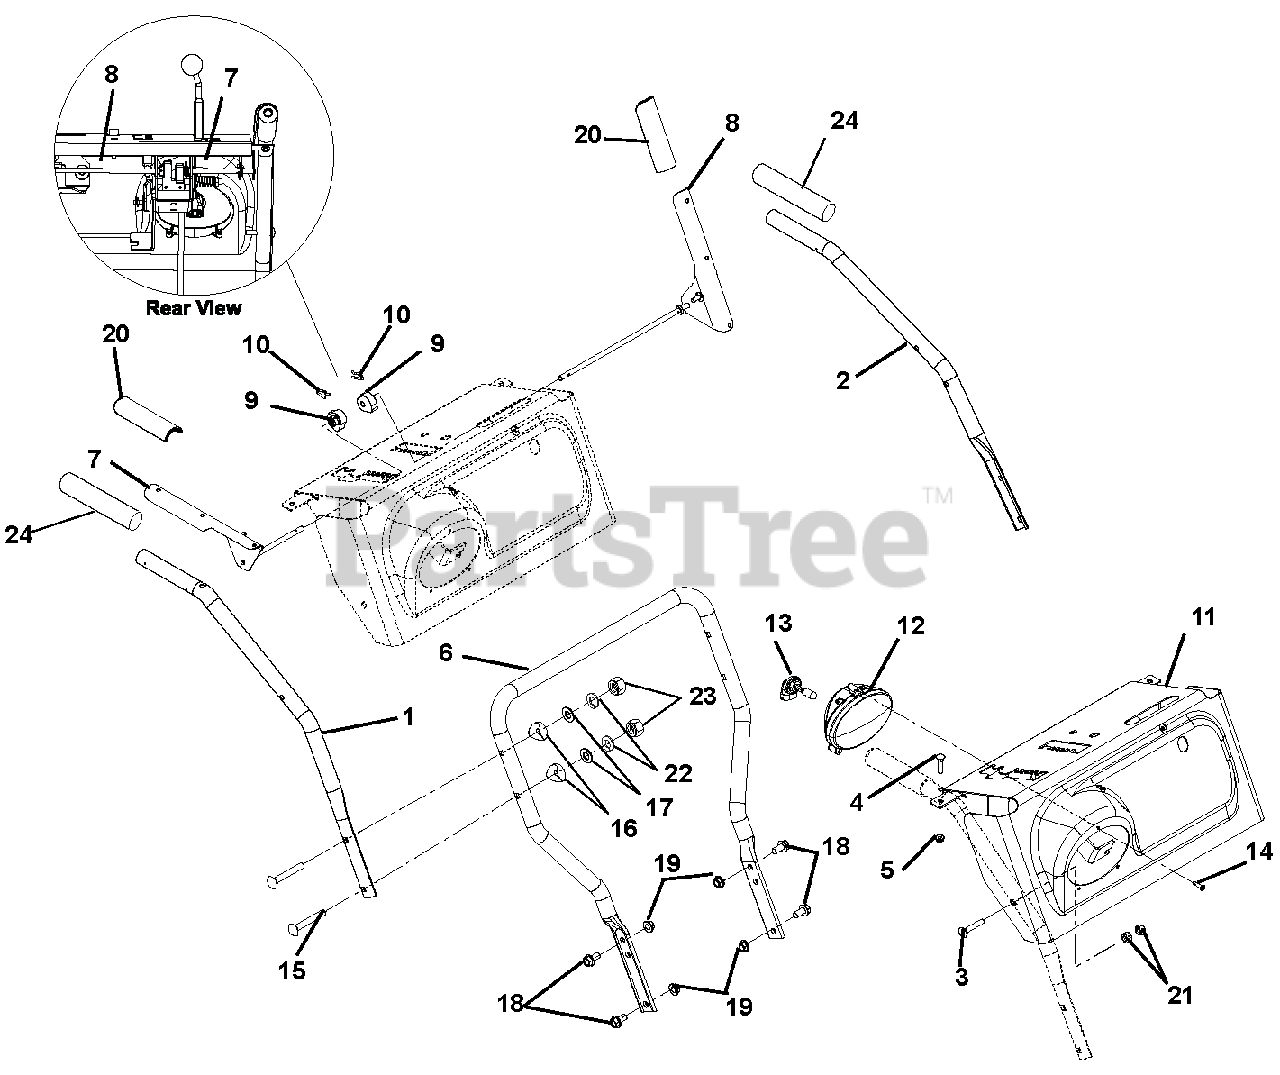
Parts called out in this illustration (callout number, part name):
1	HANDLEBAR, UPPER-RH
2	HANDLEBAR, UPPER-LH
3	@BLT-RDHDSQNK .31-18X1.75 G5YZ
4	BLT-RDHDXLSQNK.25-20X1.25 G5ZC
5	@NUT-LK-TOP-FLG .25-20 YWZC
6	HANDLEBAR, LOWER
7	LEVER, RH-ATTACHMENT
8	LEVER, LH-TRACTION
9	CAM, INTERLOCK NYLON, LG DASH
10	PIN, SPRING CLIP
11	PANEL, WITH CONTROL DECAL
12	LIGHT, HALOGEN ASSY 12W
13	BULB, LIGHT, HALOGEN - 12W
14	SCR-TAP 10-16X.75 HI-LO PPH
15	@BLT-RDHDSQNK .31-18X2.25 G5YZ
16	SPACER, HANDLEBAR
17	@WSHR-FL-STL.38X.875X.083 YWZC
18	BLT-SERHFWH .38-16X.75 YWZC
19	@NUT-LK-TOP-FLG .38-16 YWZC
20	GRIP, CLUTCH LEVER, LH AND RH
21	@NUT-LK-CTR .31-18 YWZC
22	@WSHR-LK .31X.078 REG YWZC
23	@NUT-LK-NYL .312-18 YWZC
24	HANDLE GRIP
